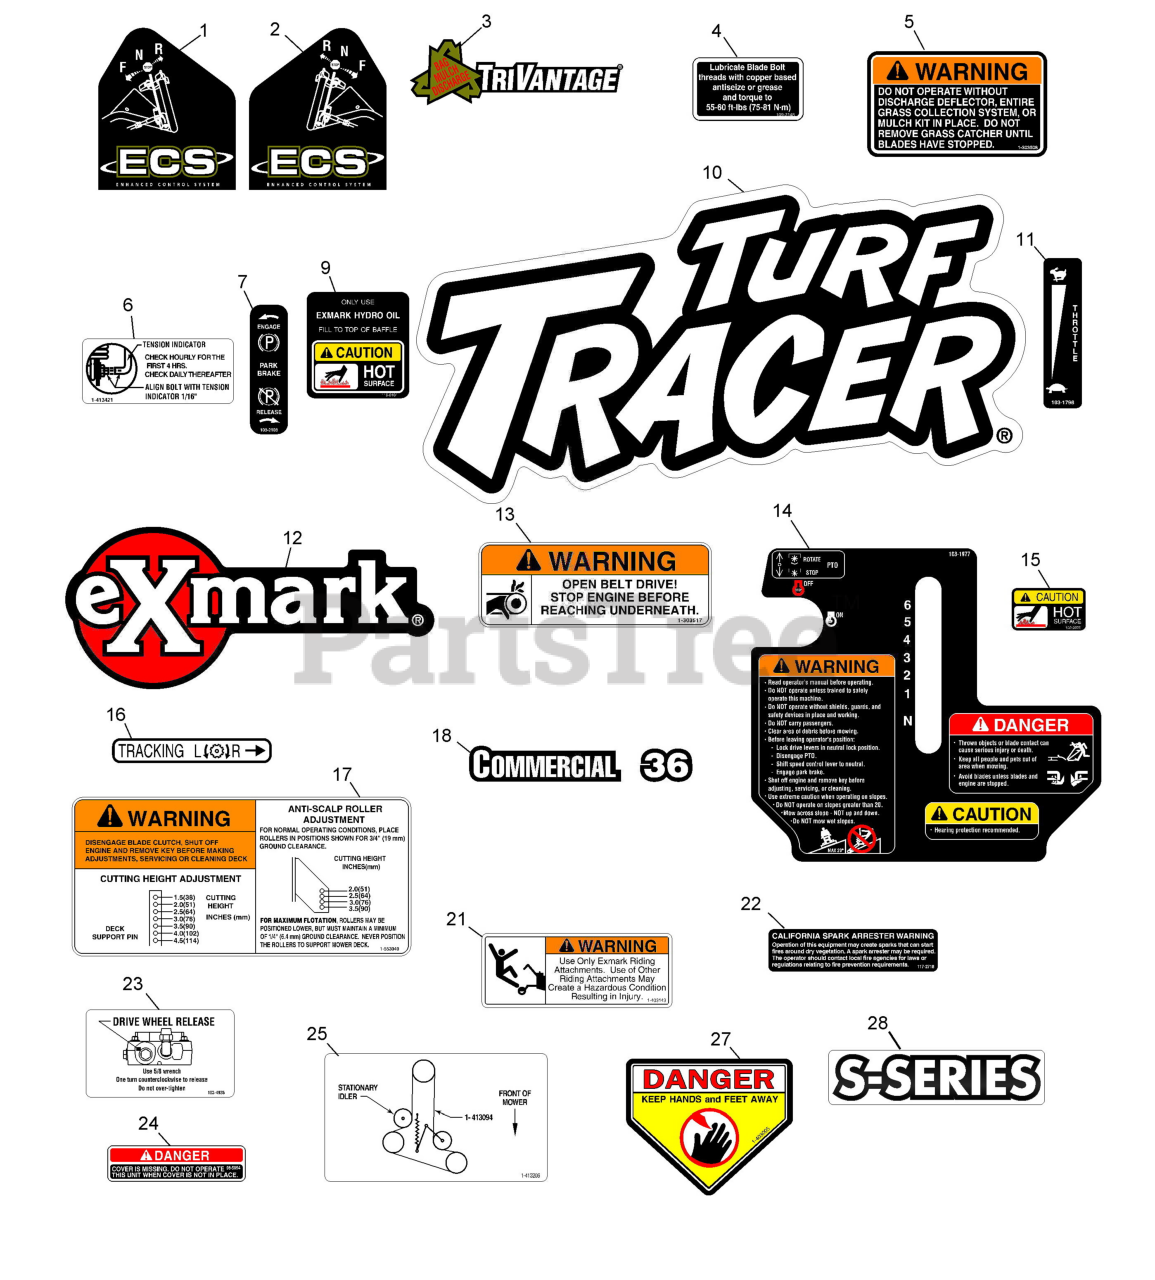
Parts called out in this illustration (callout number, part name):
1	DECAL,LH ECS INSTRUCTION
2	DECAL,RH ECS INSTRUCTION
4	DECAL,BOLT TORQUE
5	DECAL-WARNING, DISCHARGE
6	DECAL,INDICATOR
7	DECAL-BRAKE, PARK
9	DECAL-HYDRAULIC TANK
10	DECAL,TTH MODEL
11	DECAL,THROTTLE ONLY
12	DECAL,EXMARK LOGO
13	DECAL,BELT DRIVE
14	DECAL,ECS CONSOLE
15	DECAL-CAUTION
16	DECAL,TRACKING ADJUST
17	DECAL,ANTI SCALP
18	DECAL,COMMERCIAL 36
21	DECAL,SULKY WARNING
22	DECAL-ARRESTER, SPARK
23	DECAL,DRIVE RELEASE
24	DECAL-COVER, MISSING
25	DECAL,BELT ROUTING
27	DECAL-DANGER
28	DECAL-S-SERIES
